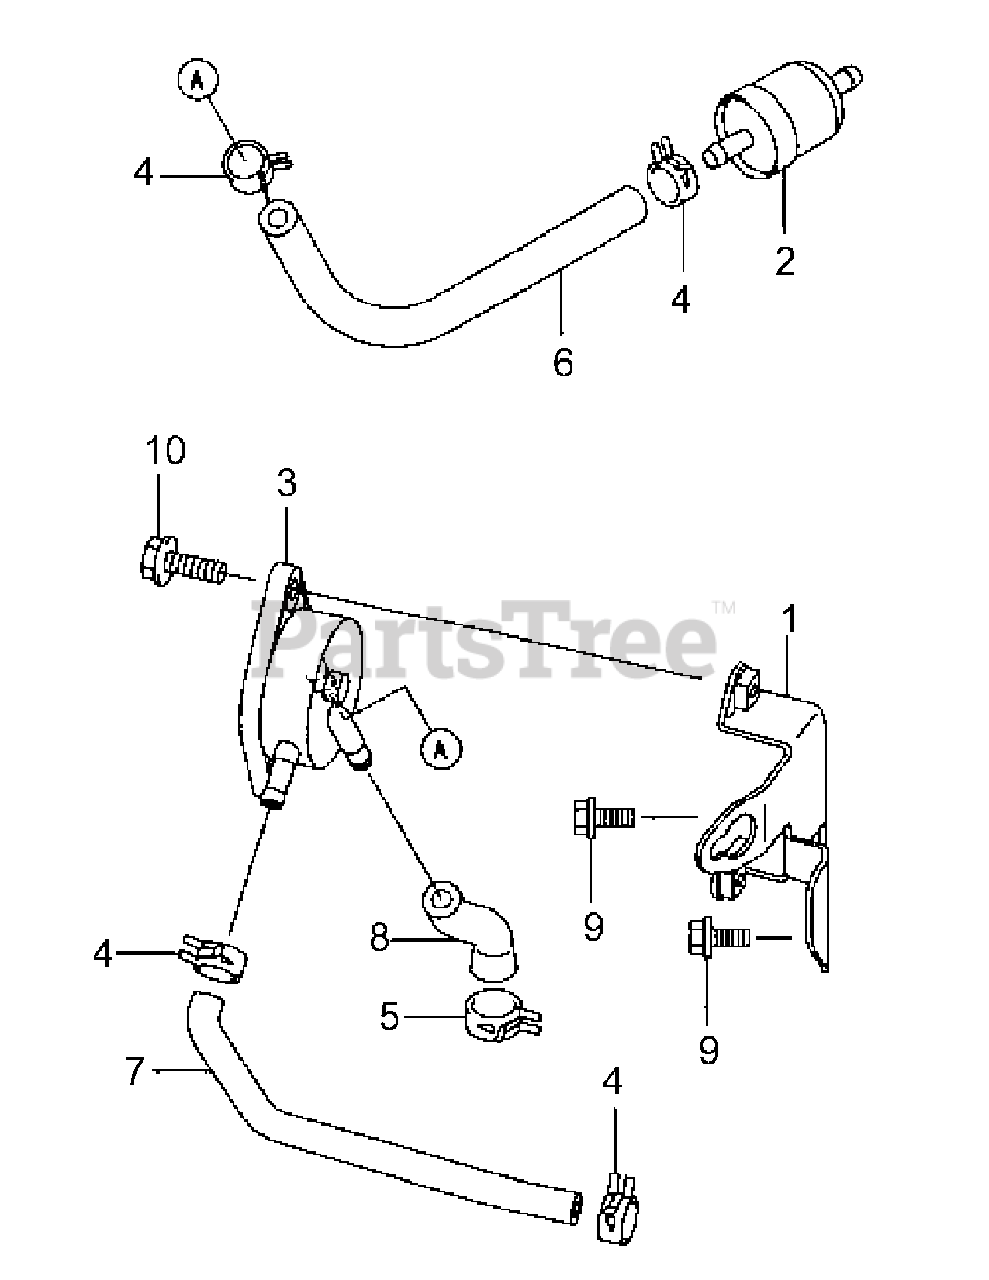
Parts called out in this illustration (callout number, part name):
2	FUEL FILTER
3	FUEL PUMP
4	CLAMP
6	TUBE, 6.35x12.7x160
9	FLANGED BOLT
10	FLANGED BOLT
